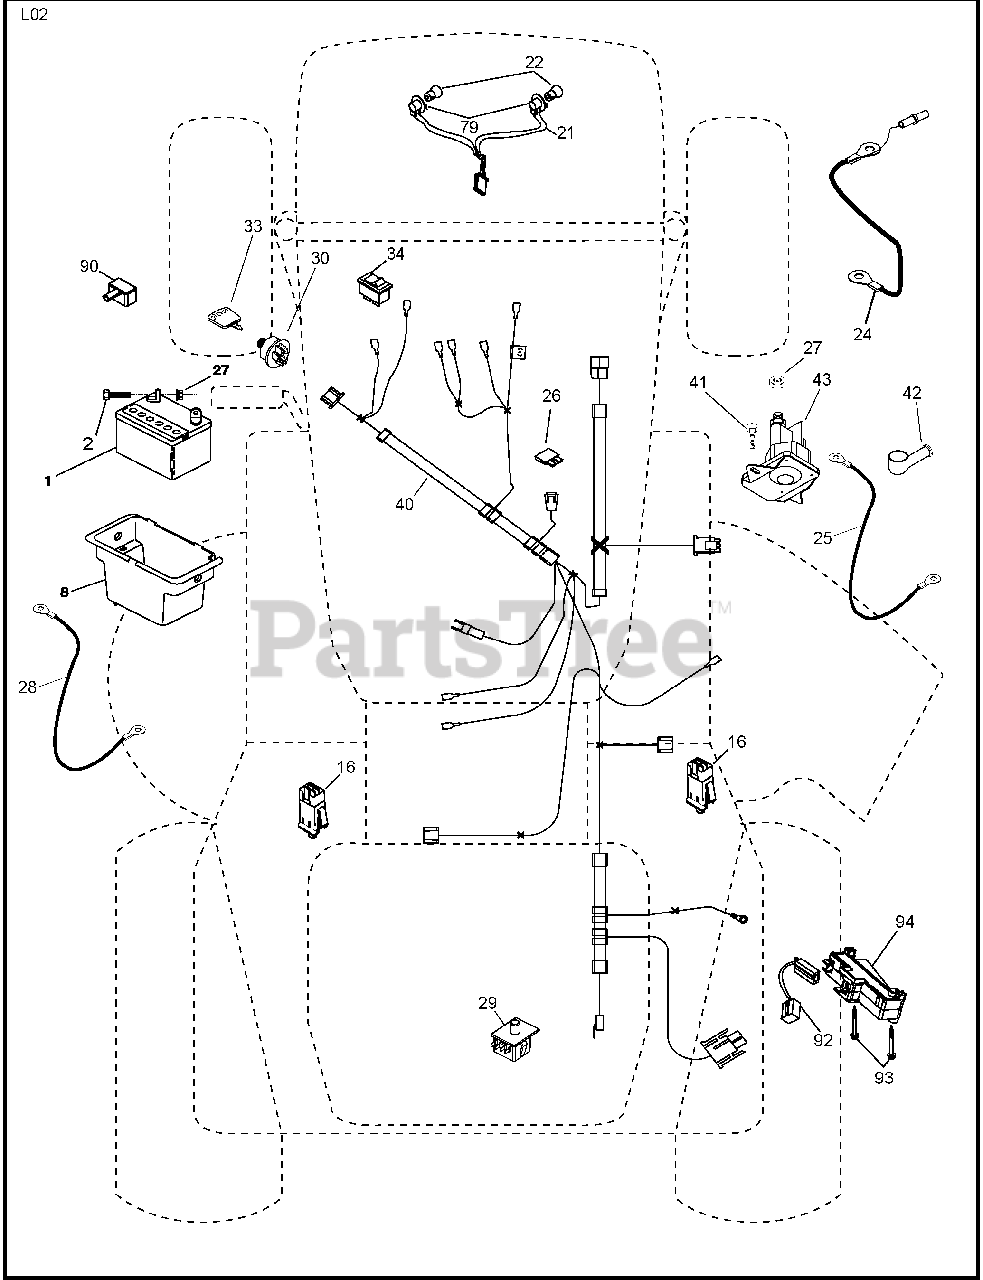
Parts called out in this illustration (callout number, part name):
1	Battery
2	Bolt Hex Hd 1/4-20 unc x 3/4
8	Box Battery
16	Switch Interlock
21	Harness Asm Light w/4152j
22	Bulb Light #1156
24	Cable Battery 6 Ga. 11" Red
25	Cable Battery
26	Fuse 20 AMP
27	Nut Keps Hex 1/4-20 unc
28	Cable Ground 6 Ga. 12" Black
29	Switch Seat
30	Switch Ign
33	Key/Chain
34	Switch Light/Reset
40	Harness Ign
41	Bolt Blk Fin Hex 1/4-20
42	Cover Terminal Red
43	Solenoid
79	Socket Asm. Bulb Twistlock
90	Cover Terminal Battery
92	Harness Pigtail
93	Screw Plastite 10-14 x 2.0
94	Module Reverse ROS
